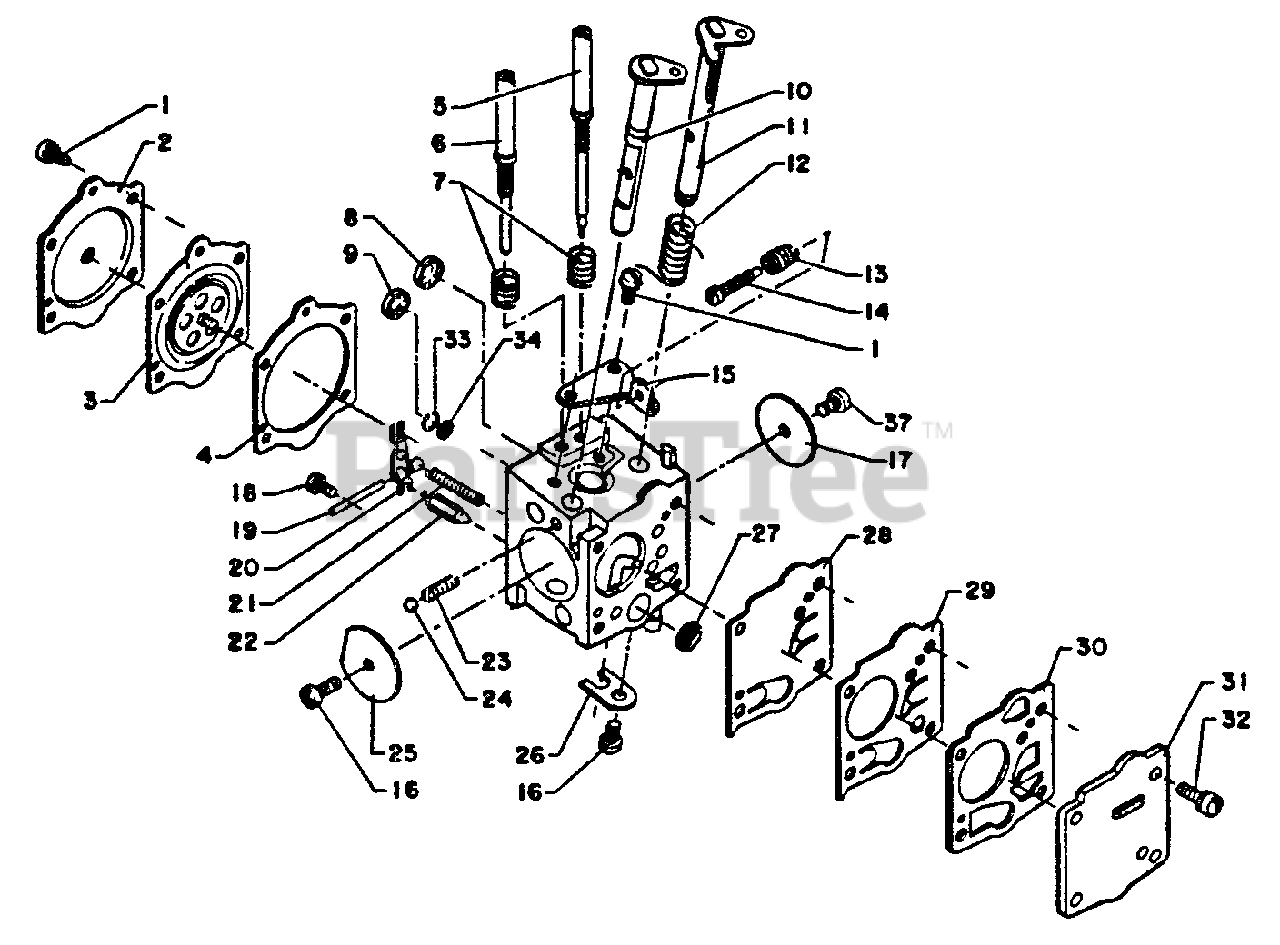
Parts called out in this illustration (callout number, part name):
1	SCREW
2	COVER, METERING
3	DIAPHRAGM
4	GASKET, METERING
5	NEEDLE - LOW SPEED
6	NEEDLE - HIGH SPEED
7	Needle adjust spring
8	PLUG, WELCH
9	PLUG, WELCH
10	SHAFT, CHOKE
11	SHAFT, THROTTLE
12	SPRING, THROTTLE RETURN
13	SPRING, IDLE ADJUST
14	SCREW, IDLE ADJUST
15	BRACKET, THROTTLE CABLE
17	VALVE, THROTTLE
18	SCREW, METERING LEVER PIN
19	PIN, METERING LEVER
20	LEVER, METERING
21	SPRING, METERING LEVER
22	VALVE, NEEDLE
23	SPRING
24	BALL, CHOKE
25	VALVE, CHOKE
26	RING, RETAINING
27	STRAINER
28	DIAPHRAGM, PUMP
29	DIAPHRAGM
30	DIAPHRAGM, GASKET
31	COVER, PUMP
32	SCREW, PUMP COVER
33	RING, RETAINING
34	STRAINER
37	SCREW
